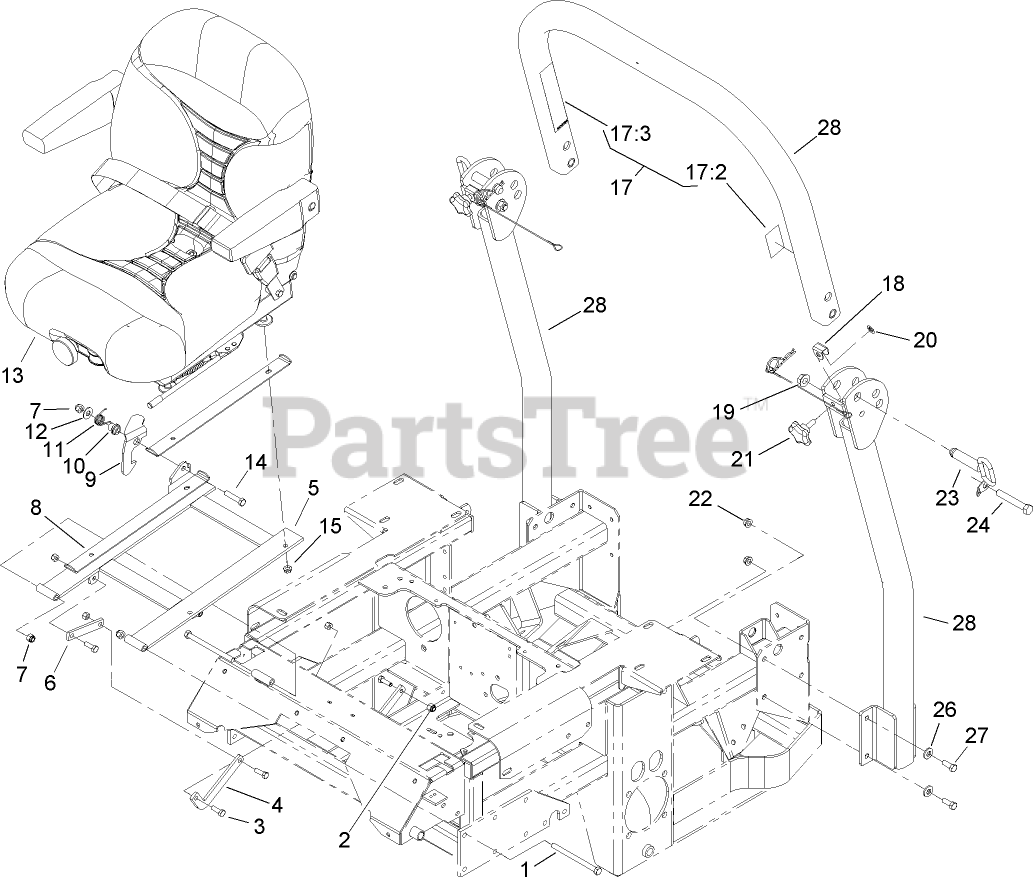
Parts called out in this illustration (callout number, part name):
1	SCREW-HH
2	NUT-LOCK, NI
3	SCREW-HH
4	LINK-SEAT STOP, LOWER
5	FRAME-SEAT
6	LINK-STOP, SEAT
7	NUT-LOCK, NI
8	STOP-SEAT
9	CATCH-LATCH, SINGLE
10	BUSHING-LATCH, SEAT
11	SPRING-TORSION, LATCH
12	WASHER-FLAT
13	SEAT-SUSPENSION
14	SCREW-HH
15	NUT-HF
17	Upper Tube ASM
17:2	DECAL-ROPS
17:3	DECAL-WARNING, FOLDING ROPS
19	NUT-HF
20	NUT-PUSH
22	NUT-HHF, WHIZ
23	PIN-FOLD, ROPS
24	SCREW-HH
26	WASHER-BELLEVILLE
27	SCREW-HH
28	ROPS ASM
